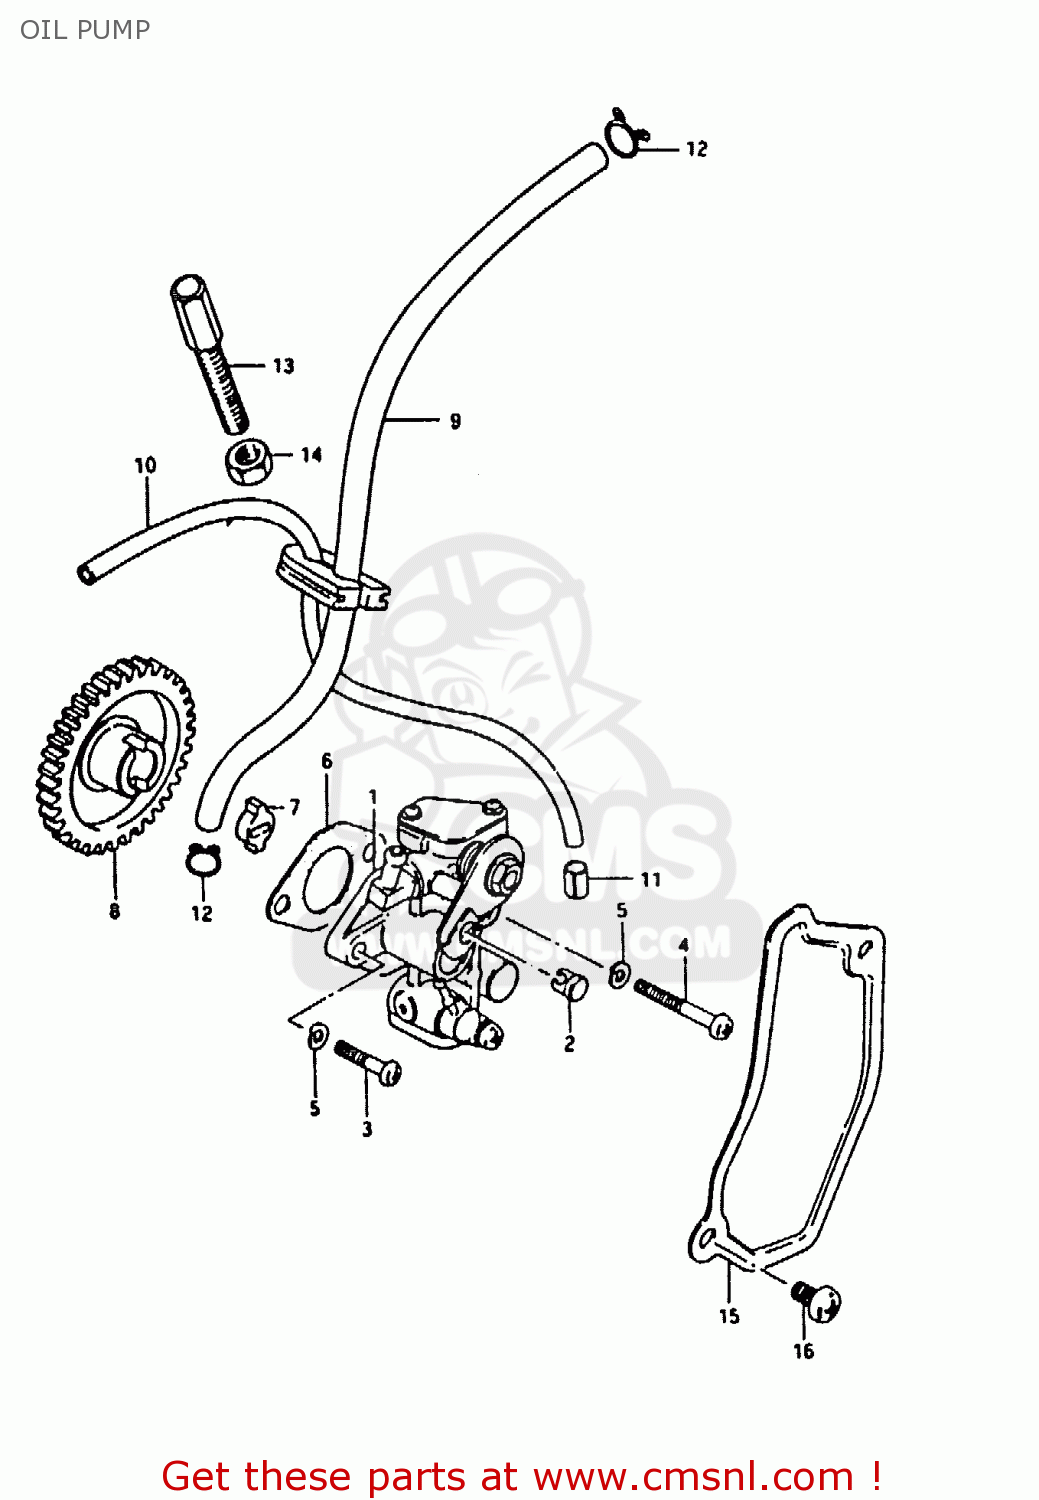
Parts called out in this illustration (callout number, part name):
1	PUMP ASSY,OIL
2	TERMINAL,CABLE
3	SCREW
4	SCREW
5	LOCK WASHER
6	GASKET,OIL PUMP (NAS)
7	PIECE,OIL PUMP DRIVE
8	GEAR,OIL PUMP DRIVE
9	HOSE
10	HOSE,NO.2
11	CLIP
12	CLIP
13	BOLT
14	NUT
15	CRANKCASE SET
16	SCREW
